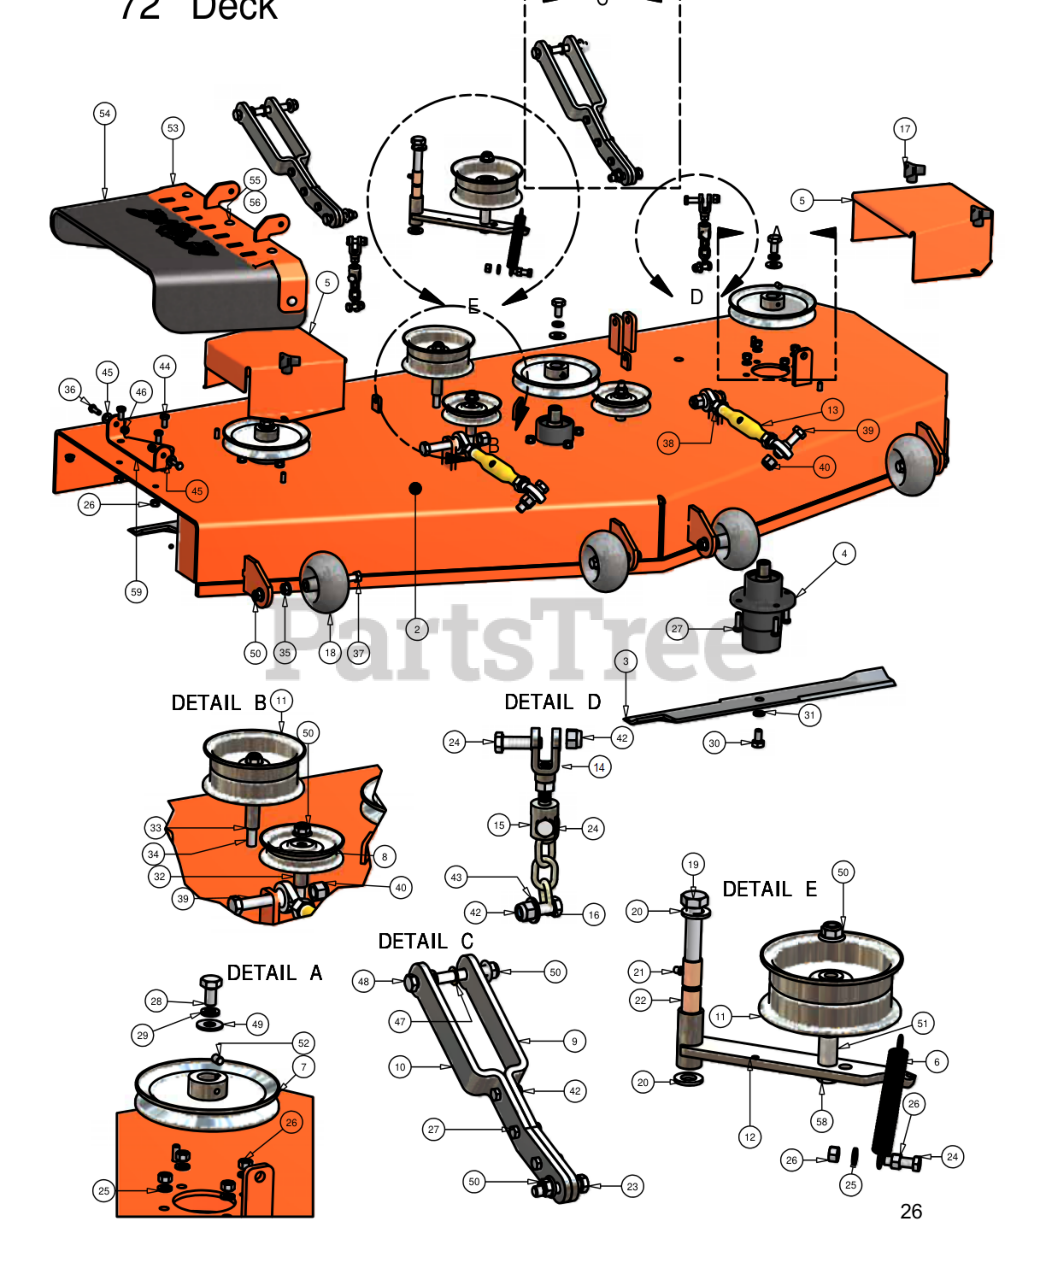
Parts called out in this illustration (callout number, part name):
1	72" Deck Belt
3	72" Fusion Blade
5	Pulley Guard
6	Deck Idler Spring
7	7" Deck Pulley
8	4 3/4" Idler Pulley
9	Deck Support Arm (Right)
10	Deck Support Arm (Left)
11	5 3/4" Flat Idler Pulley
12	Deck Idler Arm
13	Turnbuckle
14	Female Yoke
17	5/16" Knob
18	Anti-Scalp Rollers
19	5/8" x 4" Hex Bolt
20	.635 ID Plastic Washer
21	Grease Fitting (Drive-In Type)
22	5/8" ID x 1 1/8" Brass Bushing
23	1/2" x 2 1/2" Hex Bolt
24	3/8" x 1 1/4" Hex Bolt
25	3/8" Lock Washer
26	3/8" Hex Nut
27	3/8" x 1 1/4" Hex Bolt
28	1/2" x 1 1/2" Fine Thread Bolt
29	1/2" Lock Washer
30	5/8" x 1.5" Fine Threaded Bolt
31	5/8" Lock Washer
32	1 1/2" Pulley Spacer
33	1 3/4" Pulley Spacer
34	1/2" x 3 1/2" Bolt
35	1/2" Flange Nut
36	5/16" x 1" Hex Bolt
37	1/2" x 4" Bolt (Grade 8)
38	3/4" Left Handed Nut
39	5/8" x 2 1/2" Hex Bolt
40	5/8" Nylock Nut
41	3/8" Fine Threaded Jam Nut
42	3/8" Nylock Nut
43	3/8" Flat Washer
44	3/8" x 3/4" Hex Bolt
45	.360 ID Plastic Washer
46	5/16" Nylock Nut
47	1/2" Brass Washer
48	1/2" x 4 1/2" Bolt
49	1/2" Cupped Washer
50	1/2" Flange Lock Nut
51	1 1/4" Pulley Spacer
52	3/8" Set Screw
53	2007 Hanger Plate
54	Rubber Side Discharge
55	5/16" x 1 1/2" Carriage Bolt
56	5/16" Nylock Flange Nut
57	2007 Lower Hanger Plate
58	1/2" x 3" Bolt
59	2007 Lower Hanger Plate
